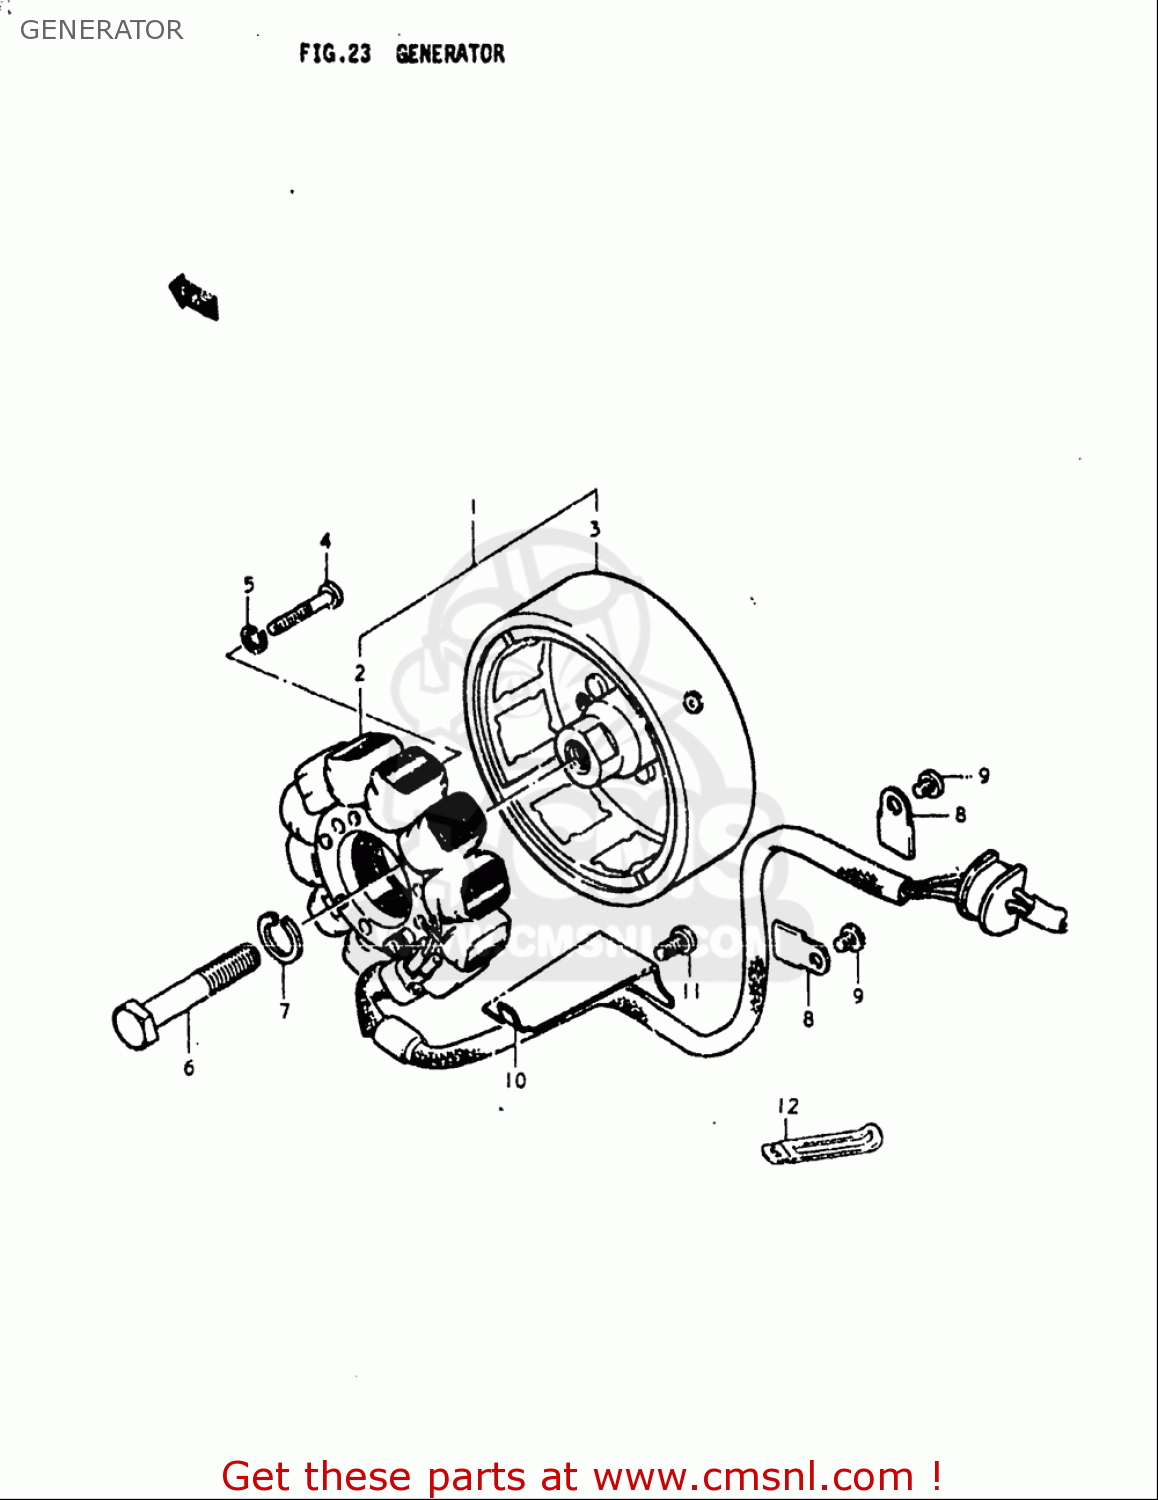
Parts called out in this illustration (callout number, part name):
1	STARTER ASSY
2	STARTER ASSY
3	ROTOR ASSEMBLY
4	SCREW
5	WASHER,LOCK
6	BOLT
7	WASHER,LOCK
8	CLAMP,GENERATOR LEAD WIRE
9	SCREW(5X6)
10	CLAMP,GENERATOR LEAD WIRE
11	SCREW
12	CLAMP(L:80 T:1.0)
